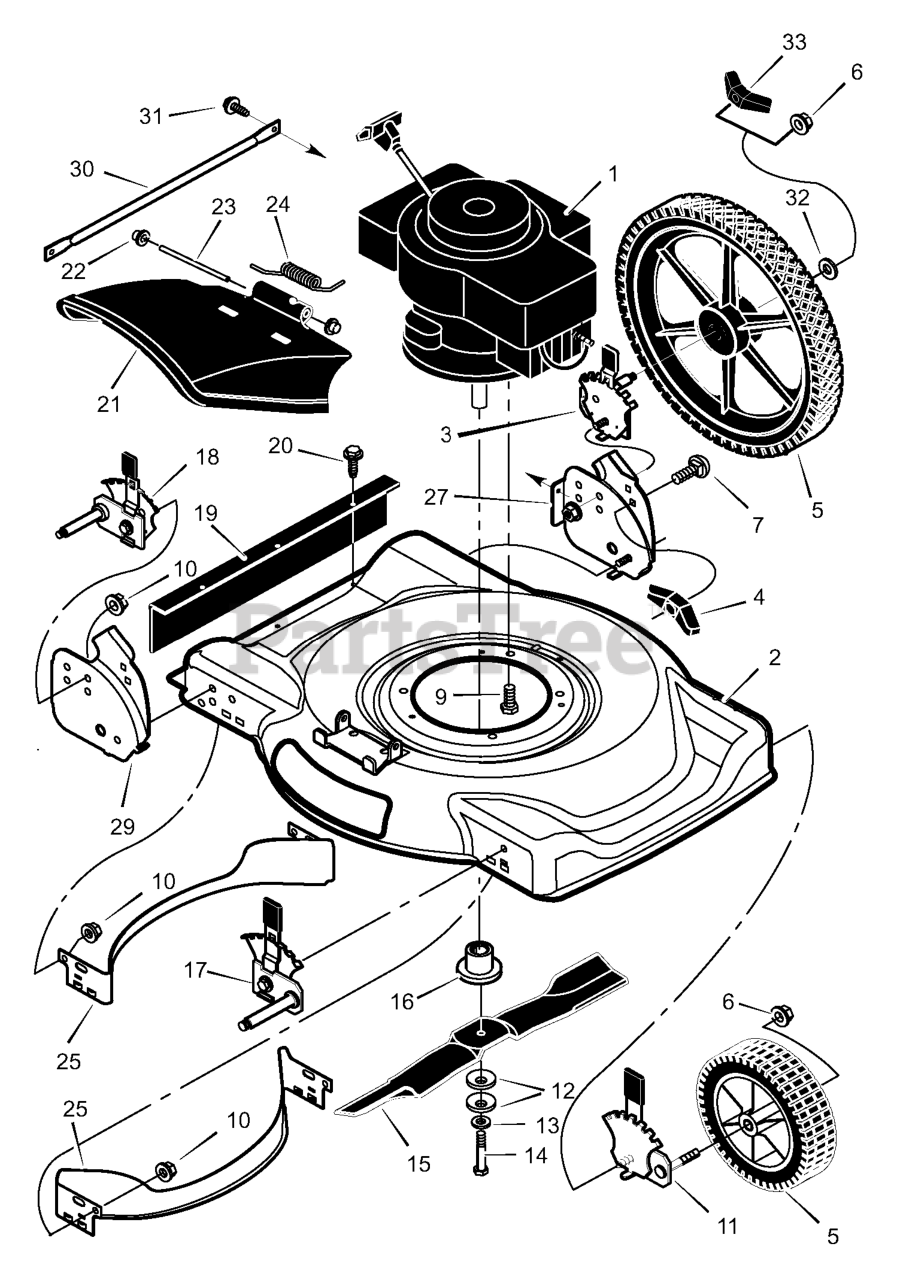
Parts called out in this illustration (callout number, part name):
1	Engine *
2	Housing
3	Height Adjuster, Left Rear
5	Wheel and Tire - Front
6	Locknut, Flange
7	Bolt, Carriage
9	Bolt, Engine
10	Nut
11	Height Adjuster, Left Front
12	Washer, Belleville
14	Bolt, Hex
15	Blade, Side Discharge
16	Adapter, Blade
17	Height Adjuster, Right Front
18	Height Adjuster, Right Rear
19	Guard, Rear
21	Deflector, Chute
22	Push-On Cap
23	Pin, Pivot
27	Bracket, Left Handle
29	Bracket, Right Handle
33	Knob, Axle
